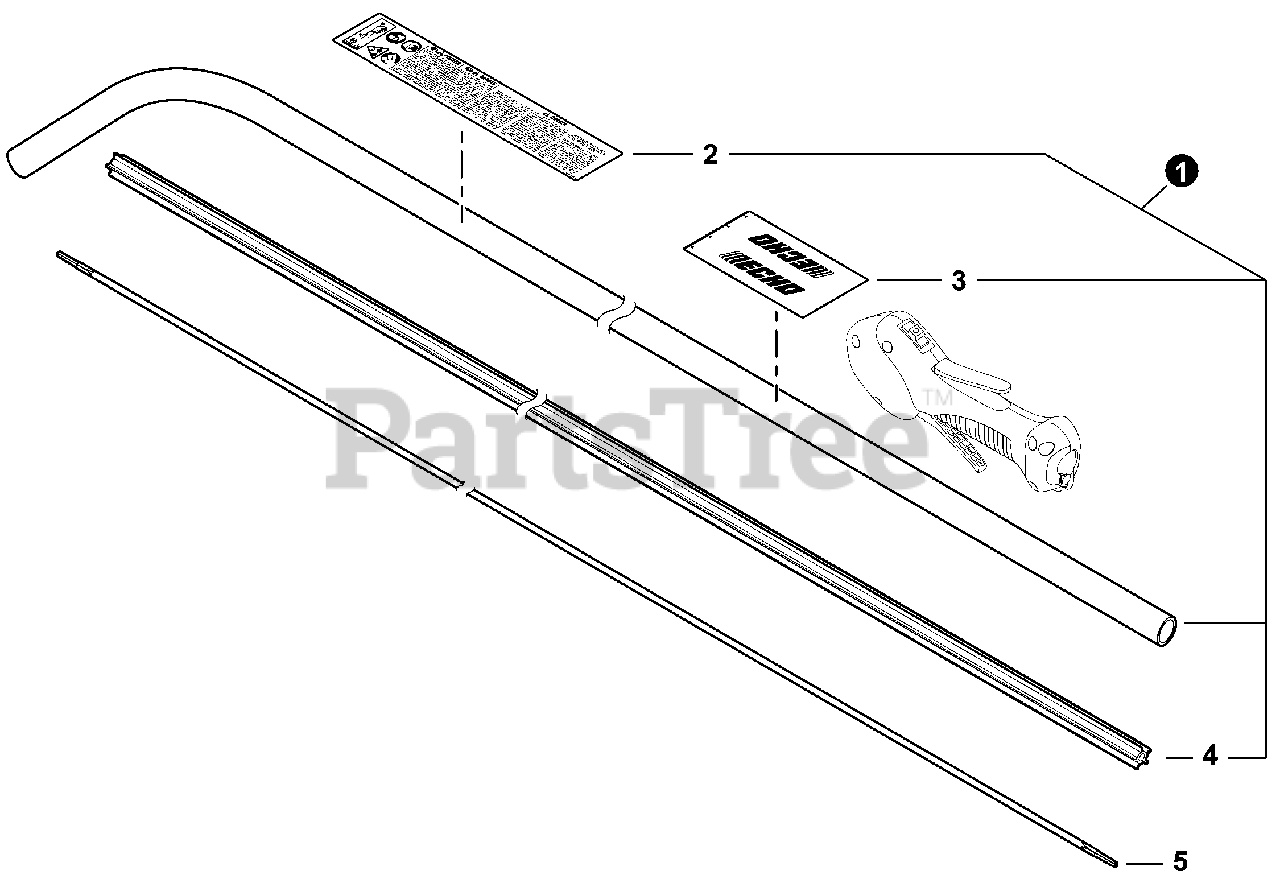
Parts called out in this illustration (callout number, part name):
1	MAIN PIPE ASSY
2	LABEL, CAUTION
3	LABEL, HANDLE LOCATION
4	LINER - FLEXIBLE
5	DRIVESHAFT - FLEXIBLE
